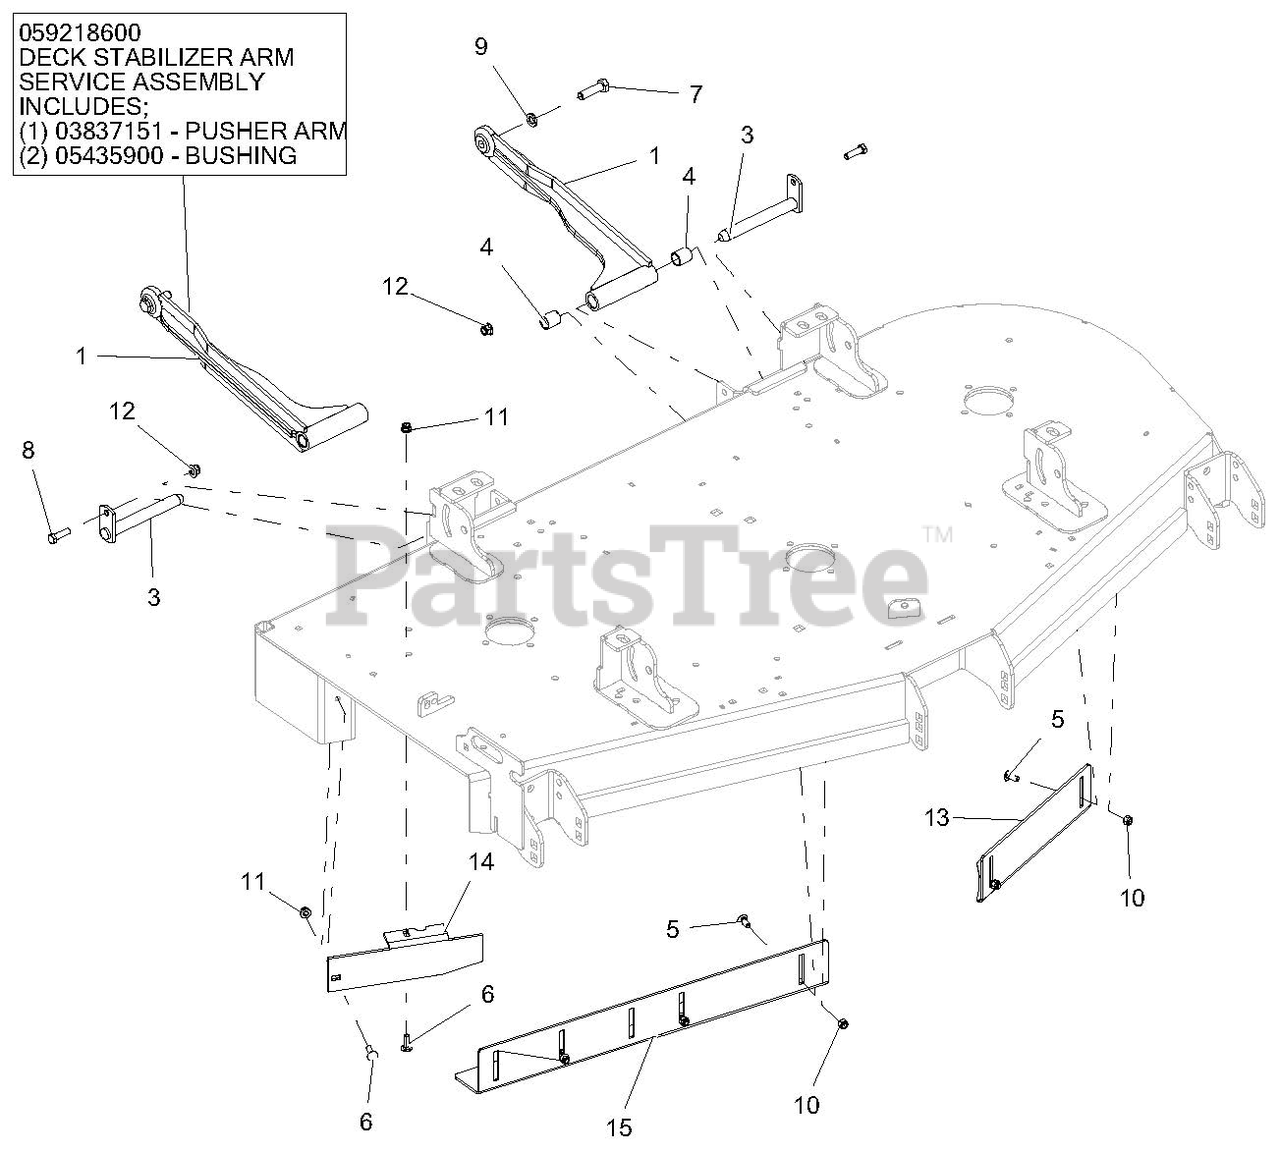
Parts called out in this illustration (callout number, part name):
1	WMT, DECK STABILIZER ARM-BLACK
1	DECK STABILIZER ARM SERVICE ASSEMBLY
1	PUSHER ARM
1	BUSHING
3	WLDMT, MOWER MTG. PIN
4	BRG, .750 X .875 X 1.000
5	BLT-RDHDSQNK .31-18X.75 G5 YWZC
6	BLT-RDHDSQSHNK .31-18X1.00 G5Y
7	BLT-HEX .50-13X1.75 GR5 YWZC EP80
8	BLT-HEX .38-16X1.25 GR5 YWZC
9	WSHR-LK .50X.125 REG YWZC
10	NUT-LK-NYL .312-18 YWZC
11	NUT-LK-NYL-FLG .31-18 YWZC
12	NUT-LK-NYL-FLG .38-16 YWZC
13	BAFFLE, 60" LH VACUUM
14	BAFFLE, 60" DISCHARGE
15	BAFFLE, 60" RH VACUUM
